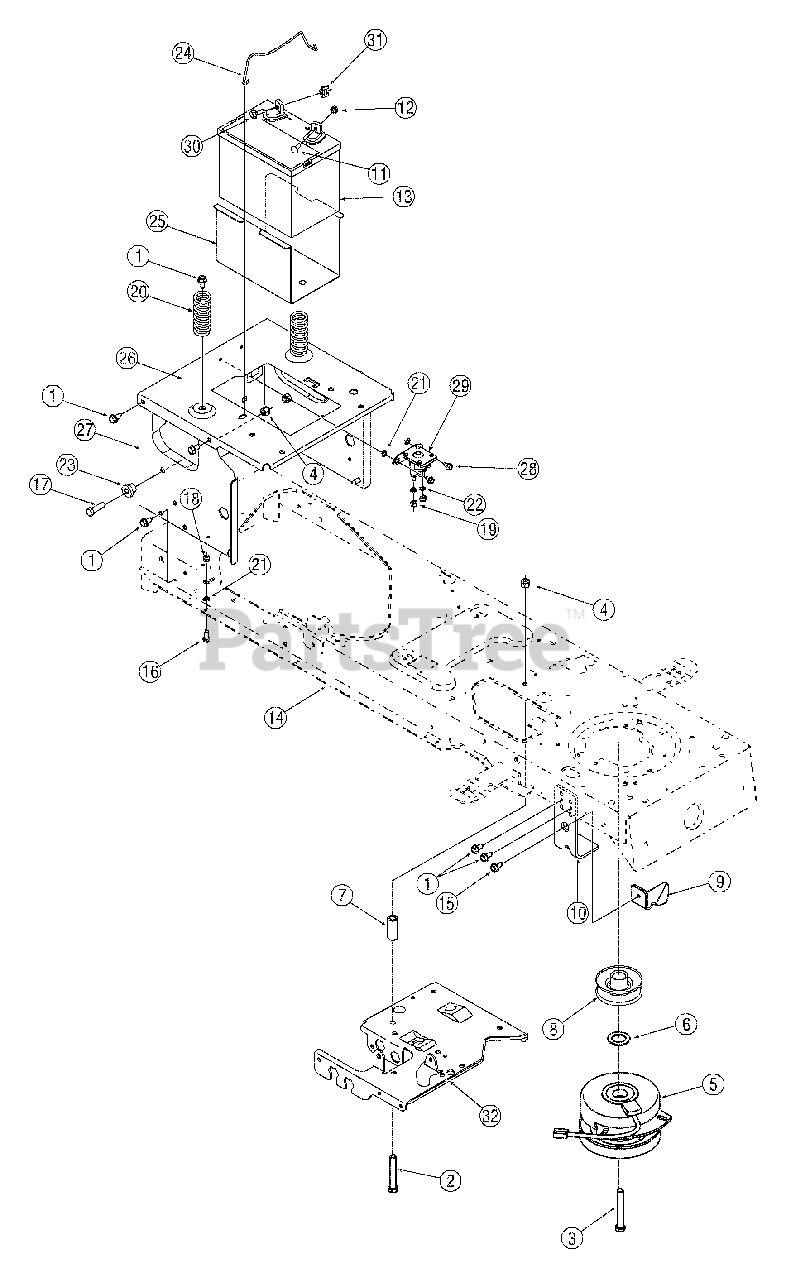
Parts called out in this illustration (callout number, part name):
1	Screw, 5/16-12, 0.75
2	Screw, 3/8-16, 2.50, Gr5
3	Screw, 7/16-20, 3.25, Gr5, Lock
4	Nut, Flange Lock, 3/8-16, Gr F, Nylon
5	PTO Clutch, Electric
6	Washer, Flat, 1.031 x 1.620 x.095
7	Spacer, .385 ID x .635 OD x 1.54
8	Pulley, Engine, 3.56 Diameter
11	Screw, Carriage, 1/4-20, .75, Gr5
12	Nut, Sems, 1/4-20
13	Battery, 235 CCA
16	Screw, 1/4-20, 0.750
17	Screw, 3/8-16, 1.25, Gr5
18	Nut, Flange Lock, 1/4-20, Gr F, Nylon
19	Nut, Hex, 1/4-20, Gr5
20	Spring, Compression, 1.28 OD x 3.125
21	Washer, Lock, 1/4, External
22	Washer, Lock, 1/4
23	Spacer, Shoulder, .38 x 1.0 x .70
24	Hold Rod, Battery
29	Solenoid, 12V, 100 Amp
30	Screw, Shoulder, .250 x .15, 1/4-20
31	Nut, Wing, 1/4-20
